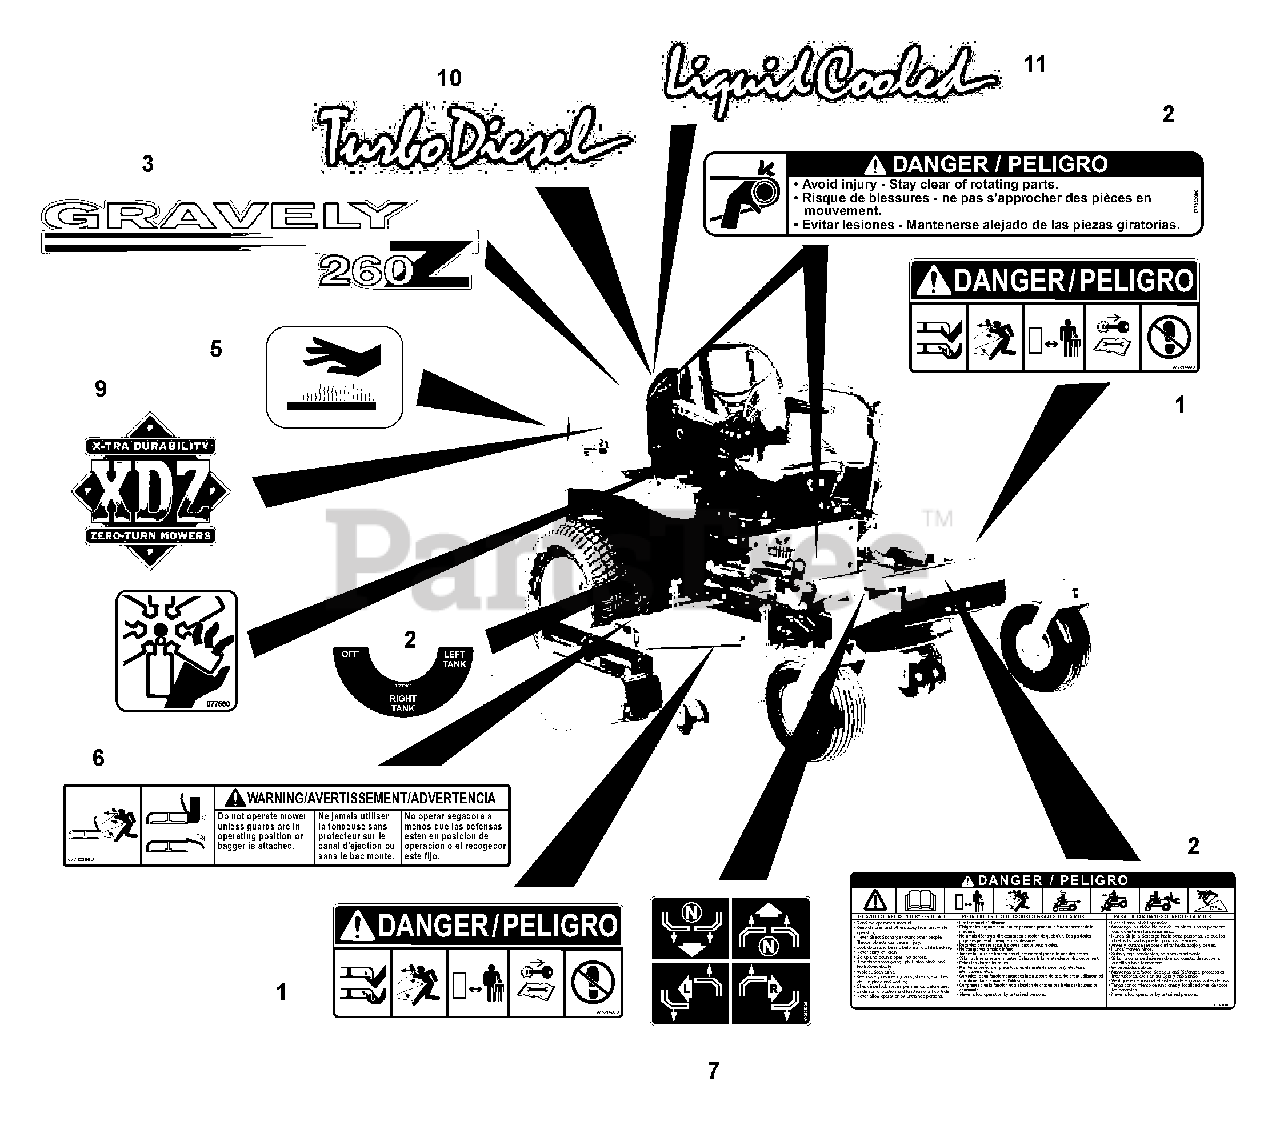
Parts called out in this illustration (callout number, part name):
1	Decal, Mower Pan Head Danger
2	Set, Decal-Common Danger/Fuel
3	Decal, PM-260Z Hood
4	Decal, PM-272Z Hood
5	Decal, Hot Surface
6	Decal, Warning
7	Decal, Instructional
8	Decal, Danger Fan
9	Decal, XDZ
10	Decal, Turbo Diesel
10	Decal, Diesel
11	Decal, Liquid Cooled
